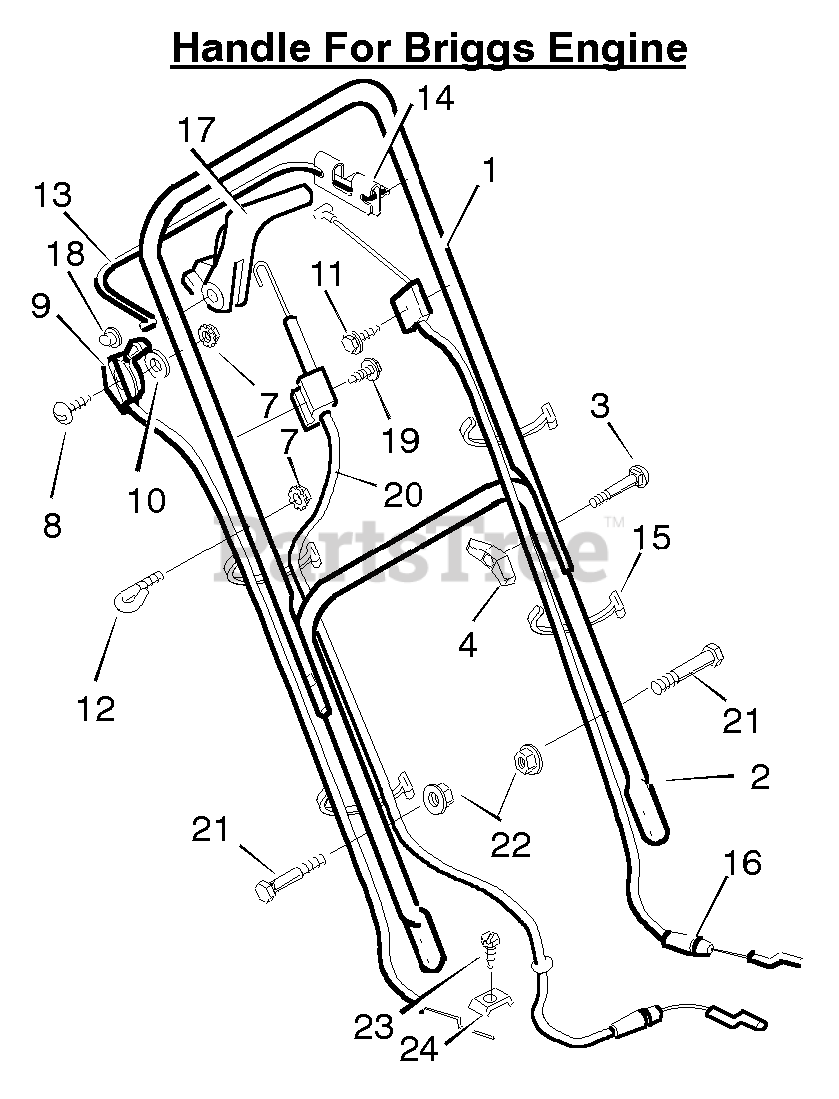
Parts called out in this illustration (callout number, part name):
1	Handle, Upper
2	Handle, Lower
4	Knob
7	Locknut
9	Throttle Control
10	Washer
12	GUIDE, ROPE
13	Lever, Engine Stop
14	Bracket, Stop Lever
15	Fastener, Cable
16	Cable, Engine Stop
17	Lever, Drive
18	Push On Cap
20	Cable, Drive
